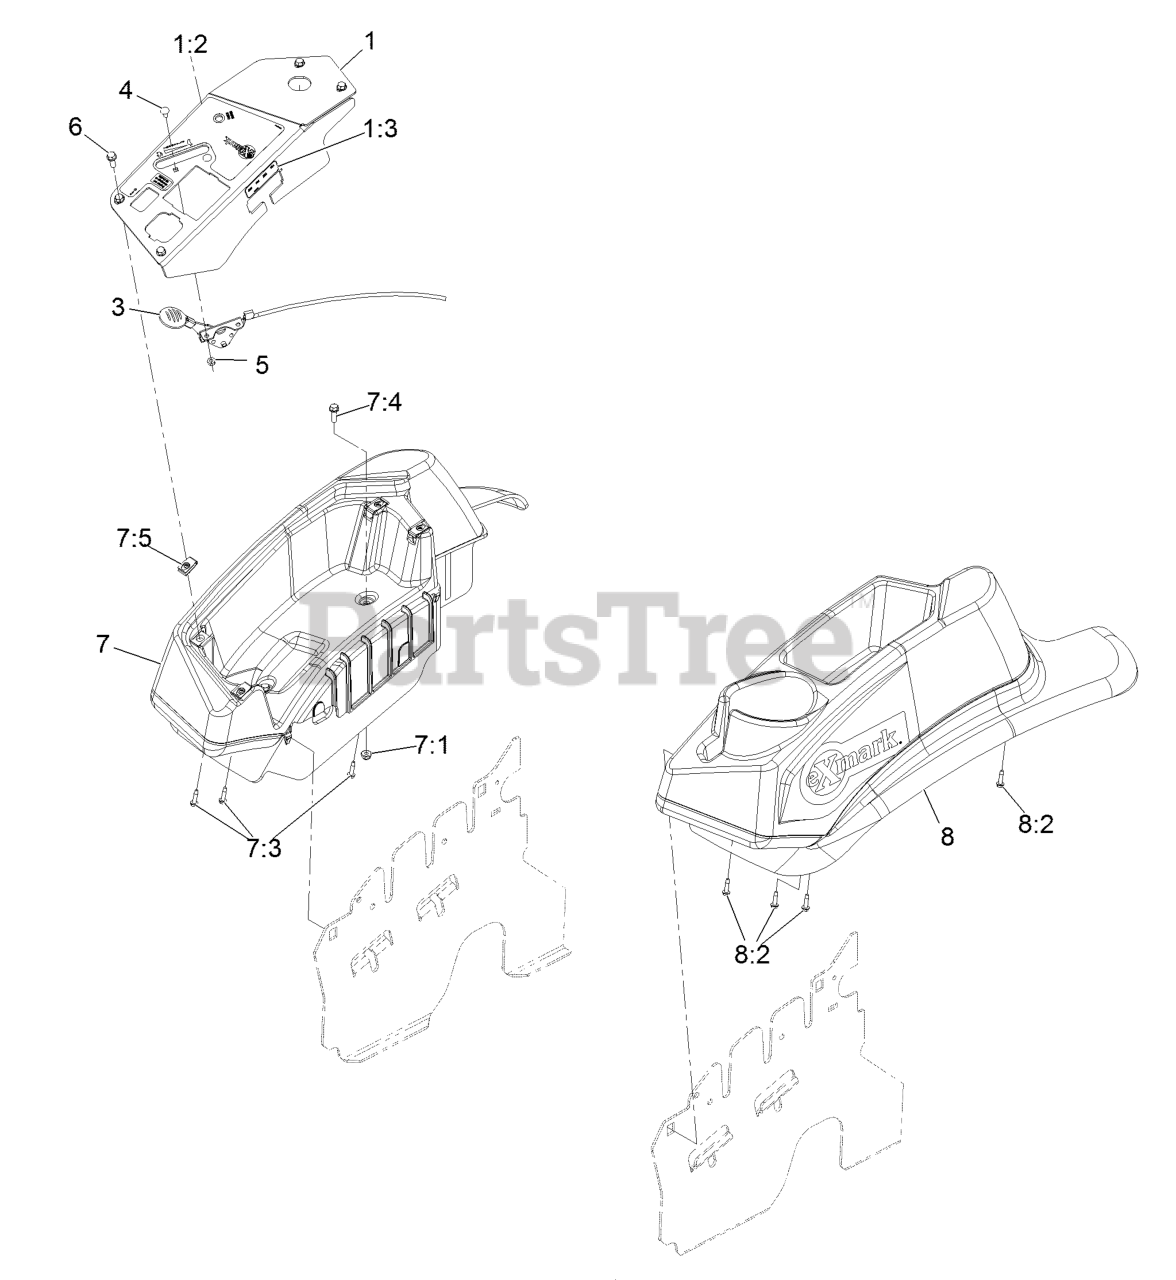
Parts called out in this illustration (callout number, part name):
1	ASM,CONTROL PANEL W/DECAL
1:2	DECAL,CONTROL PANEL EFI
1:3	DECAL-FUSE
3	ASM,THROTTLE CABLE
4	BOLT-CARR
5	NUT-LOCK, NI
6	SCREW-HWH
7	CONSOLE,RH NARROW ASM
7:3	SCREW,THD FORM,HWH
7:4	SCREW-HWH
7:5	Nut-Retainer-Panel 1/4-20
8	CONSOLE.LH NARROW ASM
8:2	SCREW,THD FORM,HWH
